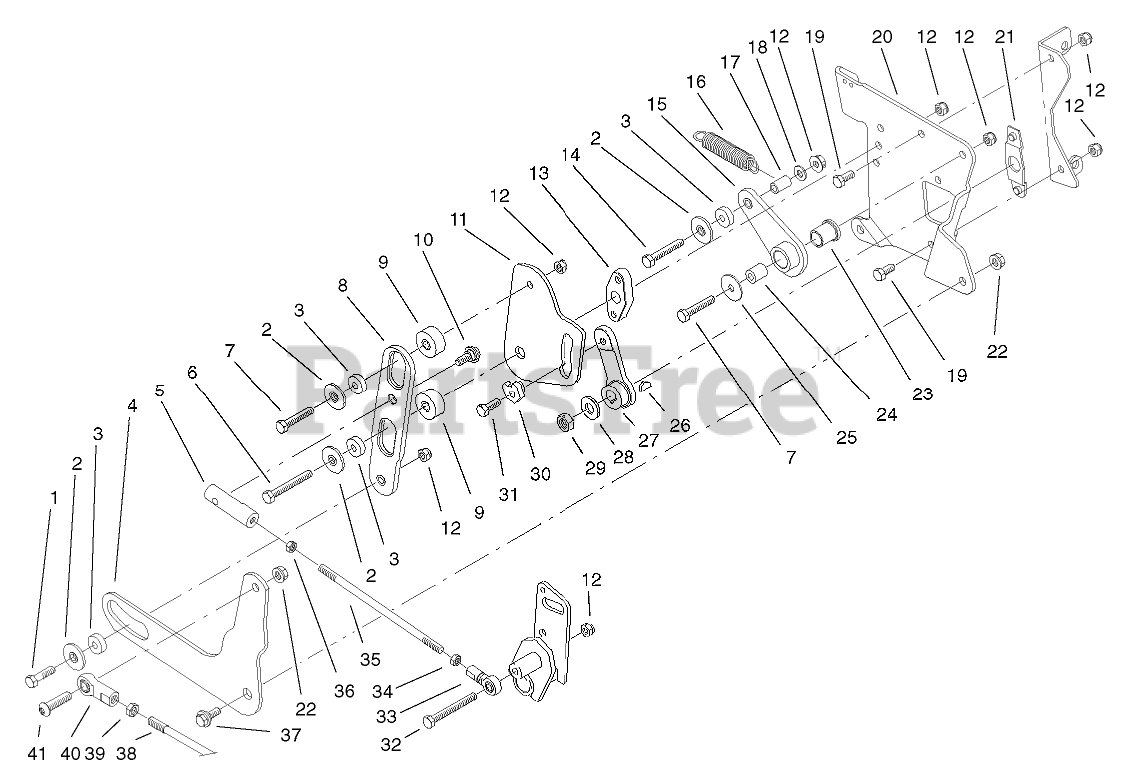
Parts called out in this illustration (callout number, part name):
1	SCREW-HH
2	RETAINER-BEARING
3	BEARING-BALL
4	SLIDER-LIFT
5	END-ROD, RH
6	SCREW-HH
7	SCREW-HH
8	SLIDER-CONTROL, SPEED
9	STANDOFF-CAM PLATE
10	BOLT-SHOULDER
11	PLATE-CAM
12	NUT-LOCK, NI
13	STANDOFF-SLIDER
14	SCREW-HH
15	ARM-RETURN TO NEUTRAL
16	SPRING-IDLER
17	STANDOFF-SPRING
18	WASHER-PLAIN
19	SCREW-HH
20	PLATE-CONTROL
21	LOCATOR-CONTROL PLATE
23	BUSHING-FLANGED
24	SPACER
25	WASHER-FLAT
26	KEY-WOODRUFF
27	ARM-CONTROL, SPEED
28	WASHER-FLAT
29	NUT-LOCK, NI
31	SCREW-THREAD LOCKING
32	SCREW-HH
33	END-ROD, RH
34	NUT-JAM
35	ROD-SLIDER TO PIVOT
36	NUT-JAM
37	BOLT-SHOULDER
38	ROD-LIFT
39	NUT-HJ
40	END-ROD, FEMALE
41	SCREW-HSBH
